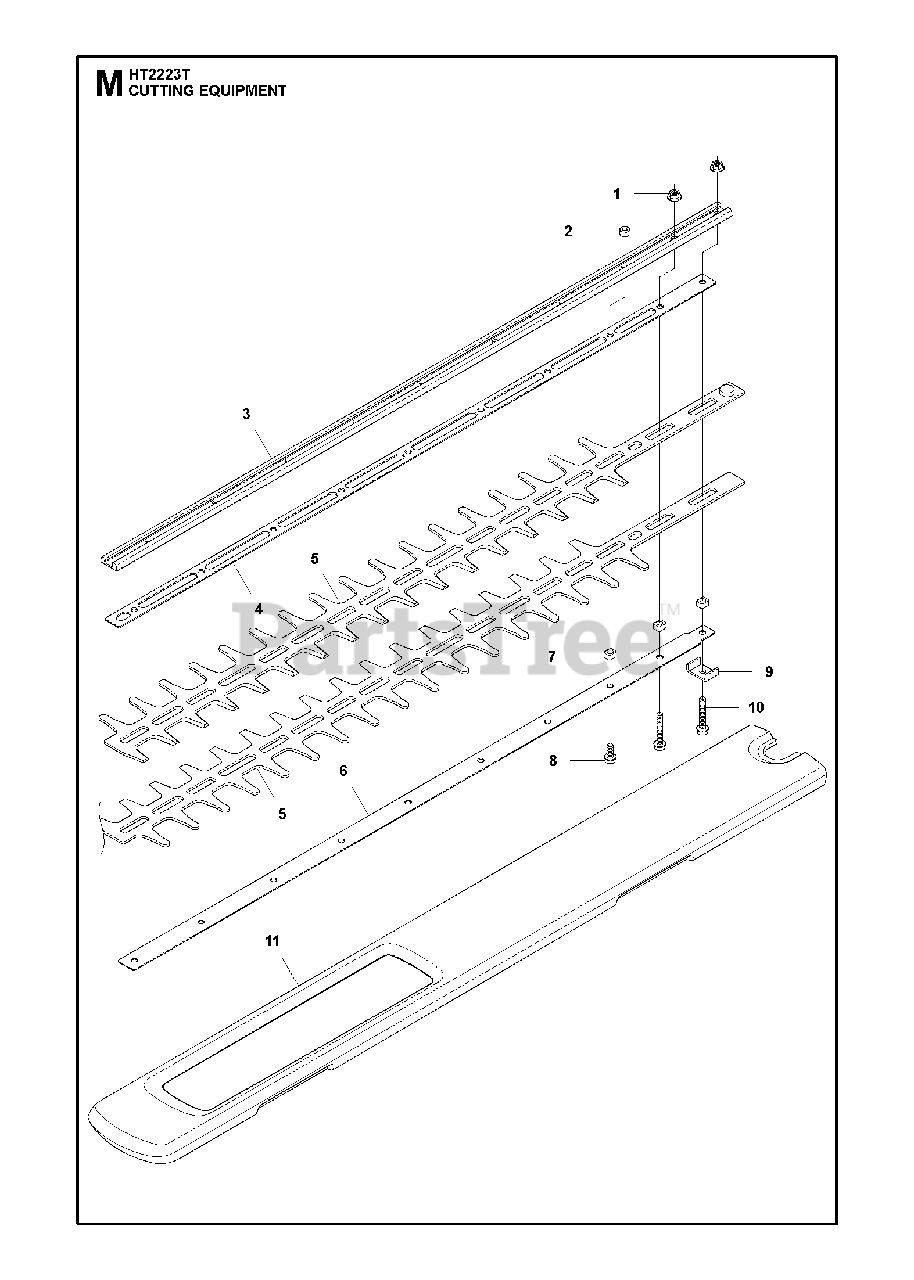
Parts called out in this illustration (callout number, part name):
4	WEAR PLATE
5	BLADE HEDGE TRIMMER
11	TRANSPORT GUARD
